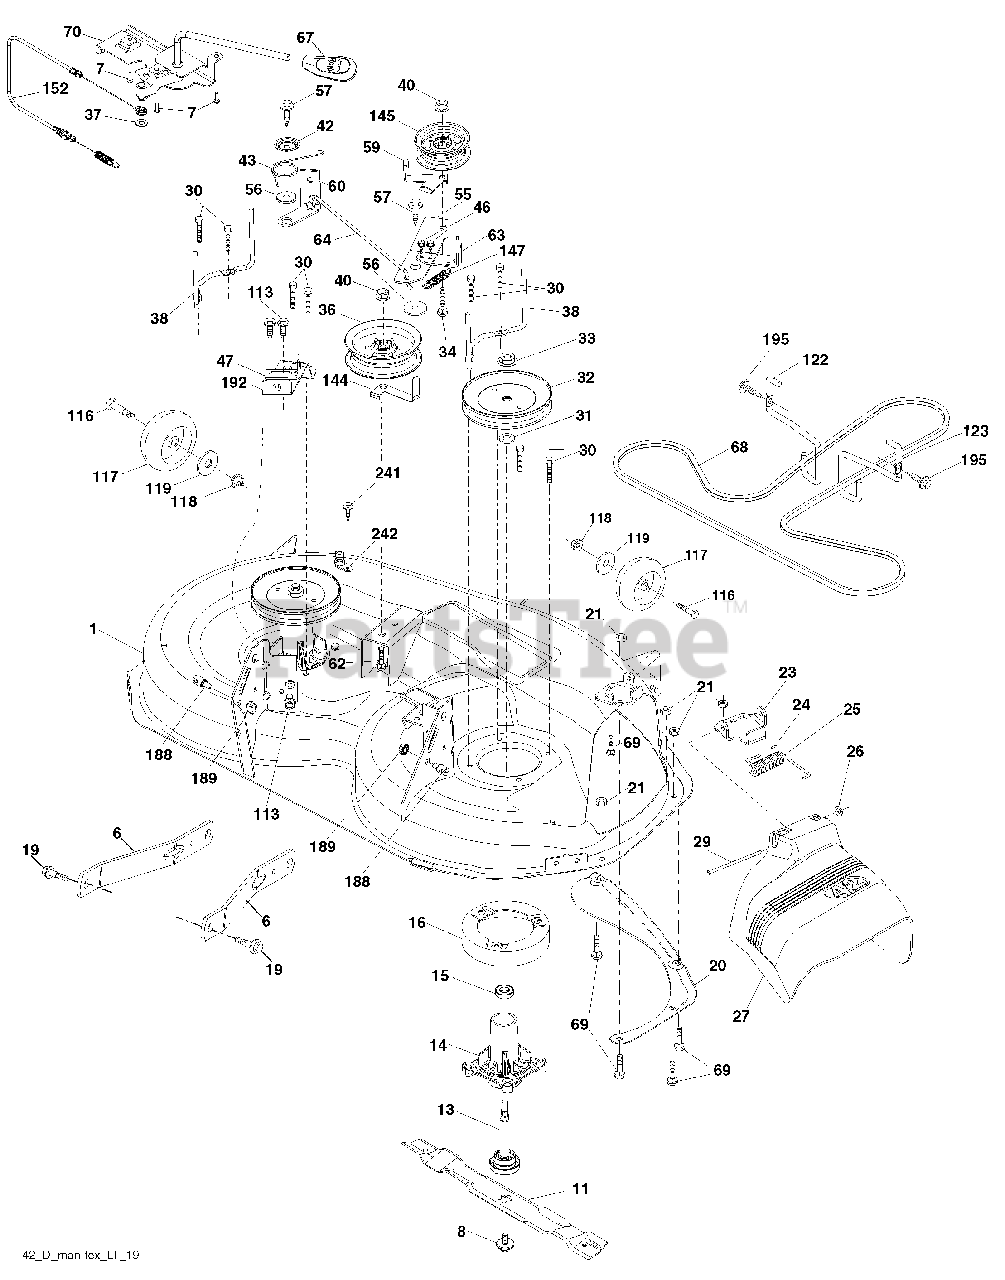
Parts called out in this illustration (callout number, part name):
1	Mower Housing
6	Arm Suspension
7	Screw #10 x 0.750 BOS Thread
8	Bolt/Washer Asm 7/16-20 unf
8	Blade, 42" Mulching Premium
11	Blade, 42" Hi-Lift
11	Blade, 42" Mulching Std
13	Shaft Assembly, Mandrel
14	Housing, Mandrel
15	Bearing, Ball, Mandrel
16	Stripper, Mower Deck
19	Bolt, Shoulder
20	Baffle, Vortex
21	Nut, Crownlock 5/16-18 unc
23	Bracket, Deflector
24	Cap, Sleeve
25	Spring, Torsion, Deflector
26	Nut, Push
27	Shield, Deflector
29	Rod, Hinge
30	Screw Thdrol Rolling Wsh Hd
31	Washer, Spacer
32	Pulley, Mandrel
33	Nut, Toplock, Flanged
34	Bolt Carr Sh. 3/8-16 x 1-1/2 Gr. 5
36	Pulley, Idler 4.50 RAW
37	Washer 13/32 x 13/16 x 16 Ga.
38	Keeper Belt LH Mandrel
40	Nut, Lock Flg. 3/8-16 unc
42	Spring Torsion Retainer
43	Spring Torsion Brake
46	Screw Thd Roll 1/4-20 x 5/8
47	Bracket Clutch Cable
55	Arm, Idler
56	Spacer, Retainer
57	Screw Hexwsh Thd 3/8-16 x 1
59	Guard, Tuv Idler (94)
60	Arm Brake Mower
62	Bolt Rdhd Sqnk 3/8-16 unc x 2
63	Arm Brake Mower
64	Linkage Brake
67	Handle, Clutch Cable
68	V-Belt
69	Bolt Rdhd Sqnk 5/16-18 x 5/8
70	Clutch Asm. Manual
113	Screw 5/16-18
116	Bolt
117	Wheel Gauge
118	Nut Lock 3/8-16 unc
119	Washer 3/8-7/8 x 14 Ga.
122	Keeper Belt Eng. LH
123	Keeper Belt Eng. RH
144	Keeper Belt
145	Pulley Idler Primary
147	Spring Return
152	Cable Clutch Manual w/Spr.
188	Stud Fastener
189	Nut Lock Hex Flange
192	Bracket Brake Stand LH
195	Screw Hexwsh Thdr 3/8-16 x 3/4
241	Vis
242	Port, Washout
242	Mandrel Assembly
242	Replacement Mower, Complete
